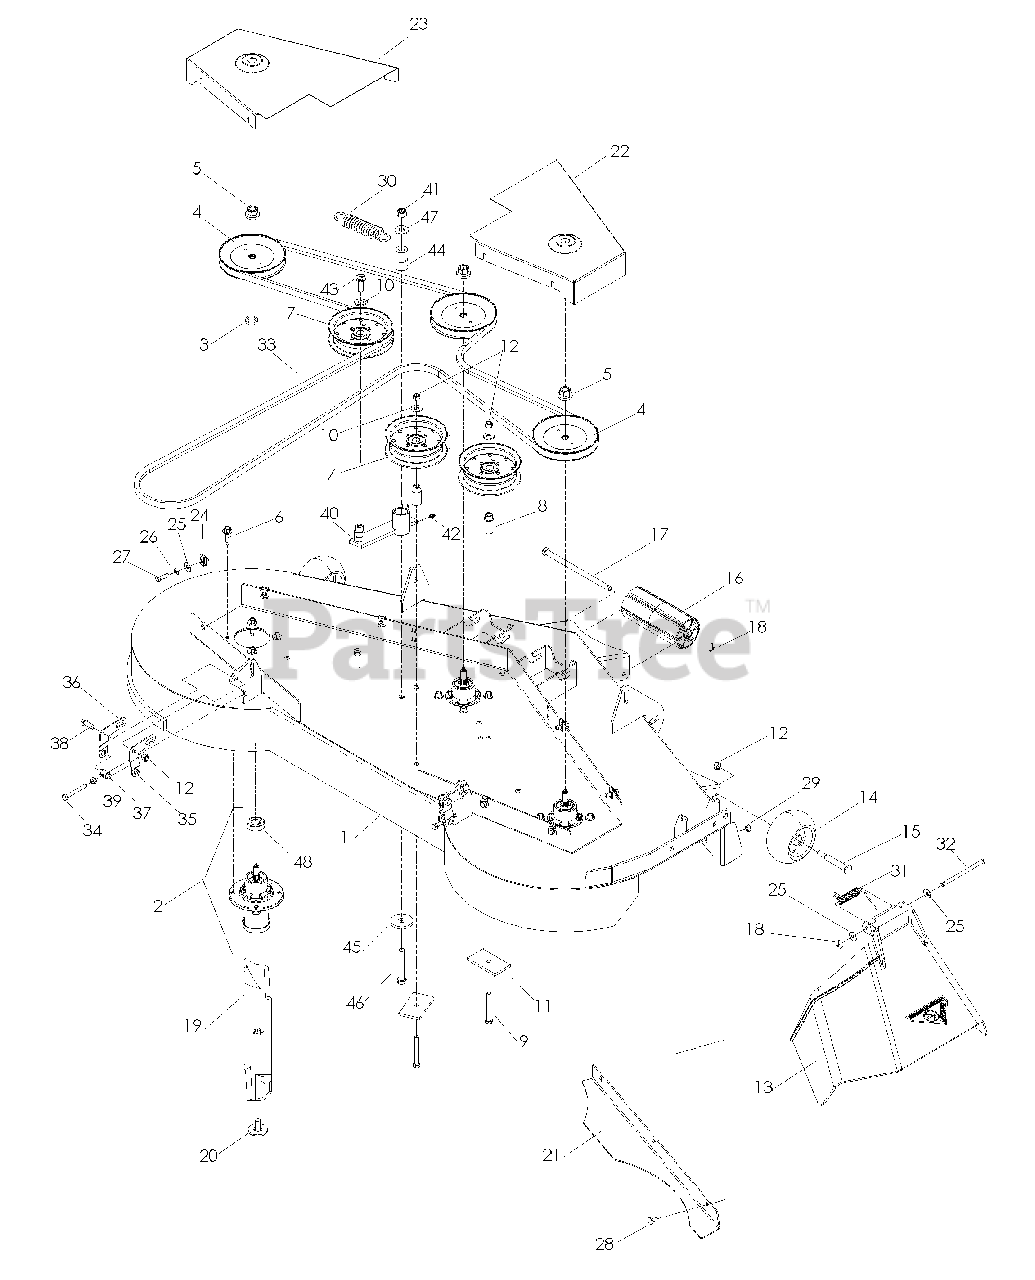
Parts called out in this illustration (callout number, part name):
1	DECK W/DECALS 61"
2	HOUSING ASSEMBLY
3	WASHER-SPACER
5	NUT 9/16 TOP CENTER LOCK
6	SCREW, WASHER HEAD
7	PULLEY, IDLER
8	IDLER BUSHING
9	HCS 3/8-16 x 3
10	WASHER, 3/8 FLAT STD
11	PAD, PAINTED
12	NUT 3/8-16 HEX NYLOC
13	DISCHARGE CHUTE, 61"
14	WHEEL, GAUGE
15	BOLT, SHOULDER
16	ROLLER, NOSE, 48"
17	ROD, ROLLER, NOSE
18	PIN, COTTER 1/8 x 3/4
19	BLADE, 21"
20	BOLT, 7/16, BLADE
21	CONFINEMENT PLATE
22	BELT SHIELD, RH
23	BELT SHIELD, LH
24	RETAINER, U TYPE
25	WASHER, 5/16 STD FLT
26	WASHER 5/16 SLW
27	HCS 5/16-18 x 1
28	RHSNB 5/16-18 x 5/8
29	NUT 5/16-18 HEX NYLOC
31	SPRING, TORSION
32	PIN, CLEVIS 5/16
33	BELT, DECK
34	HCS 5/16-18 x 2 1/2 TPBLT
35	PITCH, ADJUST, RT
36	PITCH, ADJUST, LT
37	TRUNION, PITCH
38	HCS 3/8-16 x 1
39	NUT 5/16-18 HEX
40	IDLER ARM WELDMT
41	NUT 1/2 HEX NYLOC
42	ZERK
43	HCS 3/8-16 x 1 WHIZLK
44	PIVOT BUSHING
45	SUPPORT WASHER
46	HCS 1/4-13 x 3 1/4
47	WASHER, 1/2 STD FLT
48	BALL BEARING
